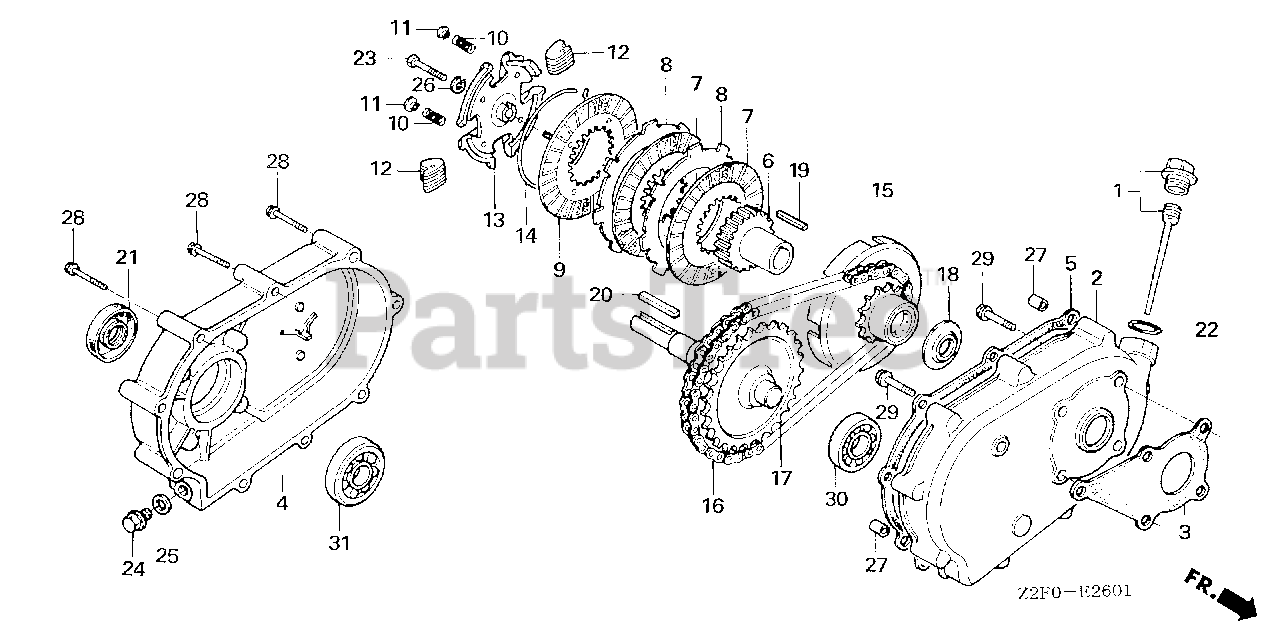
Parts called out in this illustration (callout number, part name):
1	CAP ASSY., OIL FILLER
2	CASE, REDUCTION
3	GASKET, REDUCTION CASE
4	COVER, REDUCTION
5	GASKET, REDUCTION COVER
6	CENTER, CLUTCH
7	DISK, CLUTCH FRICTION
8	PLATE, CLUTCH
9	PLATE, CLUTCH PRESSURE
10	SPRING, CLUTCH FREE
11	HOLDER, CLUTCH SPRING
12	WEIGHT, CLUTCH
13	HOLDER, CLUTCH WEIGHT
14	CENTER, CLUTCH WEIGHT
15	SPROCKET, DRIVE
16	CHAIN, DRIVE (RK428SH-36LE)
17	SHAFT, P.T.O. (28T)
18	WASHER, THRUST (20MM)
20	KEY (7X7X33) (OVER SIZE) (YELLOW)
21	OIL SEAL (30X50X7)
21	OIL SEAL (PJ30507)
22	O-RING (26X2.7)
23	BOLT, HEX. (8X35)
24	BOLT, DRAIN PLUG (12MM)
25	WASHER, DRAIN PLUG (12MM)
26	WASHER, SPRING (8MM)
27	PIN, DOWEL (8X10)
28	BOLT, FLANGE (6X55)
29	BOLT, FLANGE (8X22)
30	BEARING, RADIAL BALL (6205)
31	BEARING, RADIAL BALL (6206)
